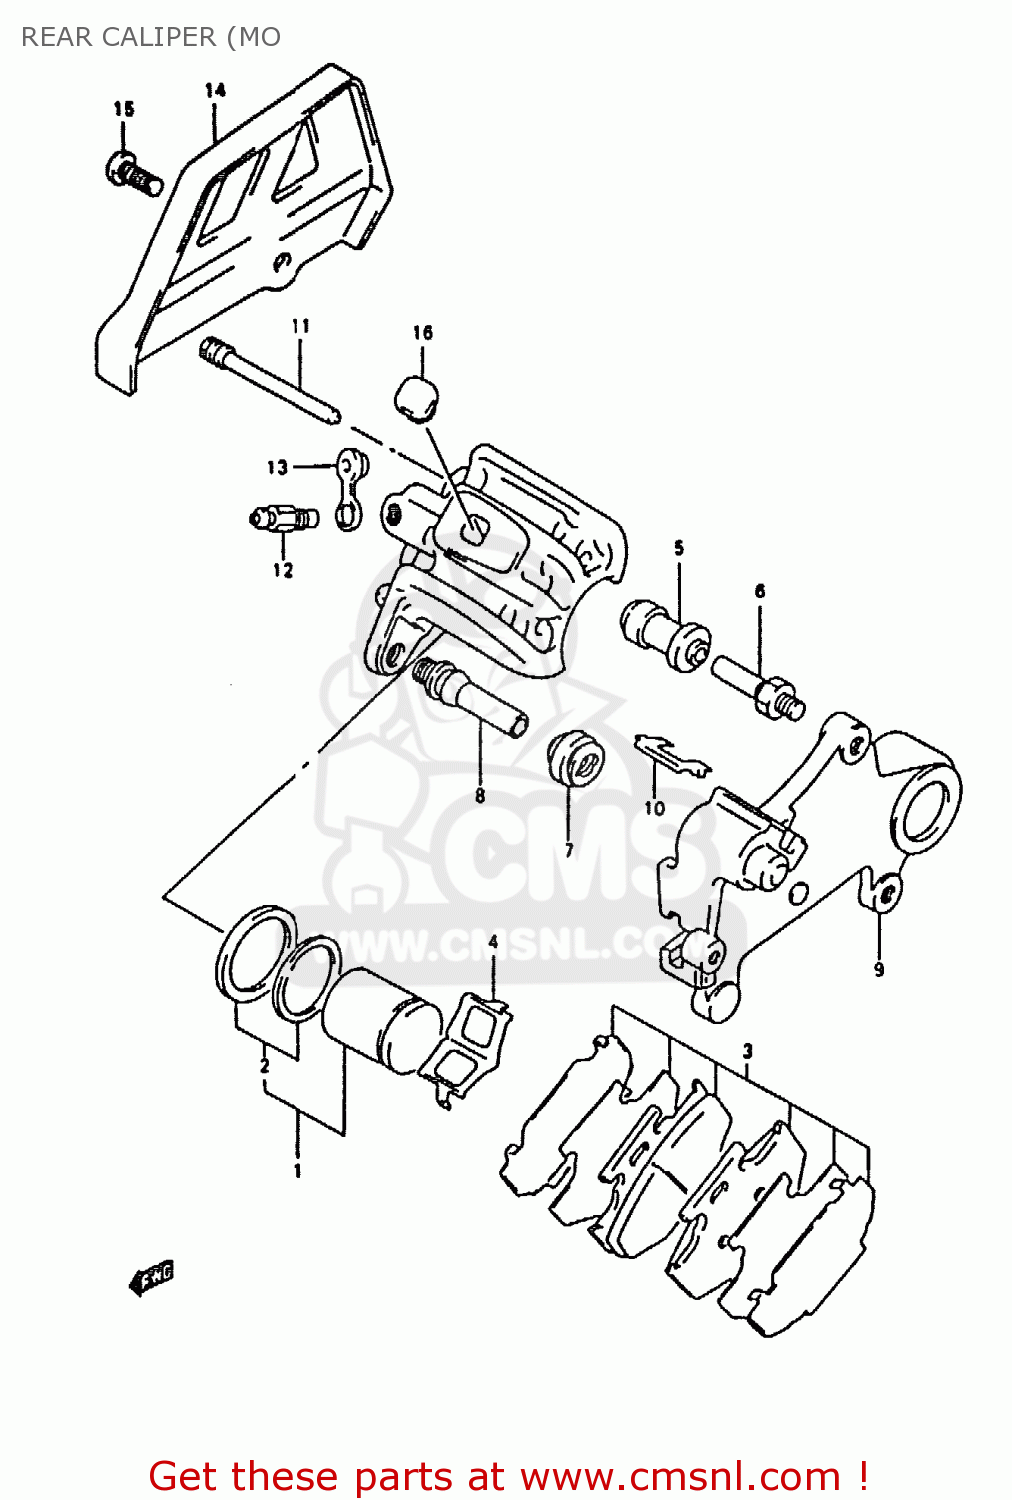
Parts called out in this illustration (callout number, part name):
1	PISTON SET
2	SEAL SET,PISTON
3	PAD & SHIM SET (NAS)
4	SPRING,PAD
5	BOOT
6	PIN,BOLT
7	BOOT
8	PIN
9	BRACKET
10	RETAINER,BRACKET
11	PIN,HANGER
12	BLEEDER
13	CAP,BLEEDER
14	GUARD SET,REAR CALIPER
15	SCREW 6X12
16	COVER,RR CALIPER BODY
17	BOLT
